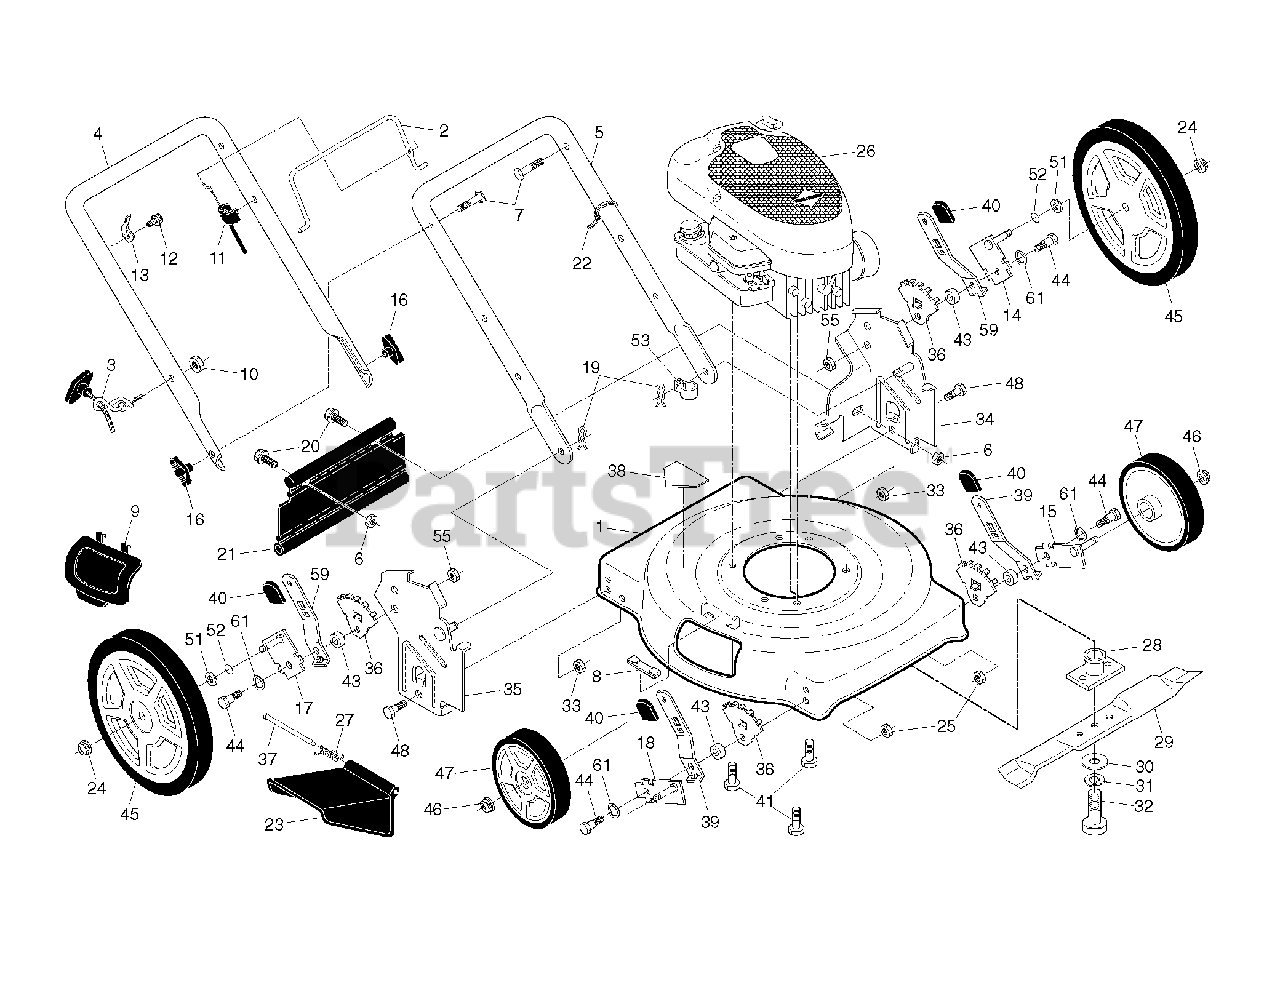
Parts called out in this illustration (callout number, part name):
2	BAIL.CONT.D.STRAIGHT.PUSH.BLK
3	Rope Guide, Blk Zinc Chrom
4	HANDLE.UPPER.ECONOMY.BLACK
5	HANDLE.LOWER.D-STRAIT.BLACK
6	LOCKNUT.NYLOC.1/4-20
7	BOLT, HANDLE 5/16-18X1.75
8	CLIP. CLOSEOUT
9	PLATE.MULCHER.22.ECON.BLACK
10	T-KNOB.NEW ROPE GUIDE
11	CABLE.MZR.RATO.22"LOW.
13	BRACKET.UPSTOP.RT
14	Axle Arm Assembly, .Lr.5/9.Pos.Bzp
15	AXLE ARM ASSY FRONT LH
17	Axle Arm Assembly, RR 5/9 Pos BZP
18	AXLE ARM ASSY FRONT RH
19	HAIRPIN COTTER
20	BOLT.HEX.1/4.X.3/4.DICHROMATE
21	SKIRT.REAR.22RD/SD.FO/VE
22	TIE GUIDE
23	GUARD.DISCHARGE.22".
24	NUT.HEX.FLANGE.3/8-16.LOCKNUT
25	NUT.FLANGE.HEX.5/16X18.BLACK
27	SPRING.HINGE
28	ADAPTOR.BLADE.7/8
29	BLADE.22.MULCH.STANDARD
30	WASHER,HARDEN
32	SCREW, HEX HD 3/8-24 X 1-3/8
33	NUT.71038.31-18.HEX.NYLOCK
34	BRKT.ASM.HDL.22.ECON.BLACK
35	BRKT.ASM.HNDL.22.ECON.HW.RH.BL
36	WHEEL ADJ BRACKET FRONT
37	HINGE ROD
38	No Step Decal
39	SELECTOR SPRING, FRONT
41	BOLT 3/8-16X1-1/8
43	SPACER.HEIGHT.ADJUSTER
44	SHOULDER BOLT 5/16-18
45	WHEEL.12X1.75.5SPK.BRK.BLACK
46	NUT.HEX.FLANGE.3/8-16.LOCKNUT
47	WHEEL.7X1.75.5SPK.BRK.BLACK
51	WASHER PM
52	O-RING..070X.487.NEOPRENE
55	NUT.LOCK.5/16-18
59	SPRING.SEL.22.ECON.HI-WHL.RATO
61	WASHER.CURVED.CYLINDRICAL
